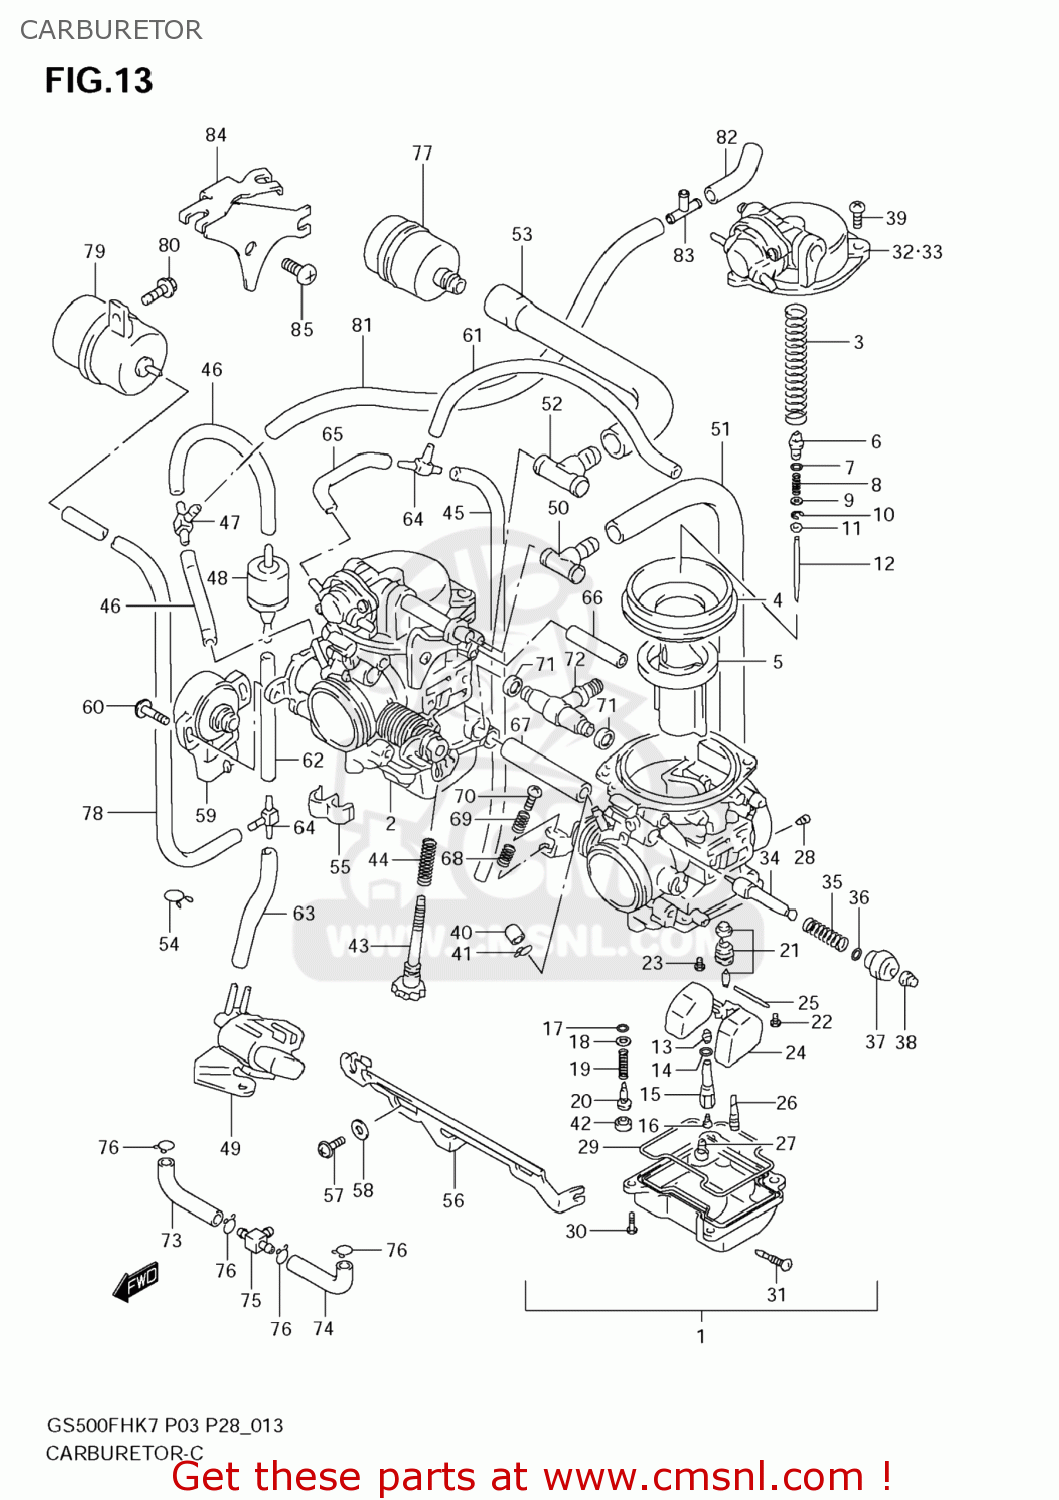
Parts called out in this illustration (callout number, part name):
1	CARBURETOR,L
2	CARBURETOR,R
3	SPRING
4	DIAPHRAGM
5	VALVE,PISTON
6	HOLDER
7	O RING(D:1.9,ID:4.8)
8	SPRING
9	WASHER
10	E RING,MULTIPLE JET NOZZLE
11	RING
12	NEEDLE, JET (5DH60-1) (E33MODEL K6 E3, E28)
13	JET,NEEDLE(P-5M)
14	O RING
15	HOLDER,JET
16	JET,MAIN(130)
17	O RING,PILOT AIR SCREW
18	WASHER
19	SPRING,THROTTLE SCREW
20	ADJUSTER
21	VALVE ASSY,NEEDLE
22	SCREW
23	SCREW
24	FLOAT ASSY
25	PIN,FLOAT
26	JET,PILOT(17.5)
27	JET,MAIN(60)
28	JET,PILOT AIR(170)
29	GASKET (NAS)
30	SCREW
31	SCREW,DRAIN
32	COVER ASSY,DIAPHRAGM,L
33	COVER ASSY,DIAPHRAGM,R
34	PLUNGER
35	SPRING
36	O RING
37	GUIDE SCREW,PLUNGER
38	CAP,STARTER VALVE
39	SCREW
40	CAP
41	CLIP
42	PLUG
43	SCREW,ADJUST
44	SPRING
45	HOSE(3.5X7.5X600)
46	HOSE(3.5X7.5X600)
47	NIPPLE
48	VALVE CHECK AS
49	VALVE ASSY,3WAY SOLENOID
50	HOSE
51	HOSE
52	3 WAY
53	HOSE
54	CLIP
55	CLIP
56	PLATE
57	SCREW
58	PACKING
59	SENSOR ASSY,THROTTLE
60	SCREW,SENSOR
61	HOSE(3.5X7.5X600)
62	HOSE(3.5X7.5X600)
63	HOSE(3.5X7.5X600)
64	3 WAY
65	HOSE(3.5X7.5X600)
66	ROD
67	PIPE
68	SPRING,THROTTLE SCREW
69	SPRING
70	SCREW
71	SEAL
72	NIPPLE
73	HOSE E33
74	HOSE E33
75	NIPPLE
76	CLIP
77	FILTER,2ND AIR CLEANER
78	HOSE(3.5X7.5X600)
79	CHAMBER,VACUUM
80	BOLT
81	HOSE(5X10X600)
82	HOSE(5X10X600)
83	JOINT,3 WAY
84	BRACKET
85	SCREW
